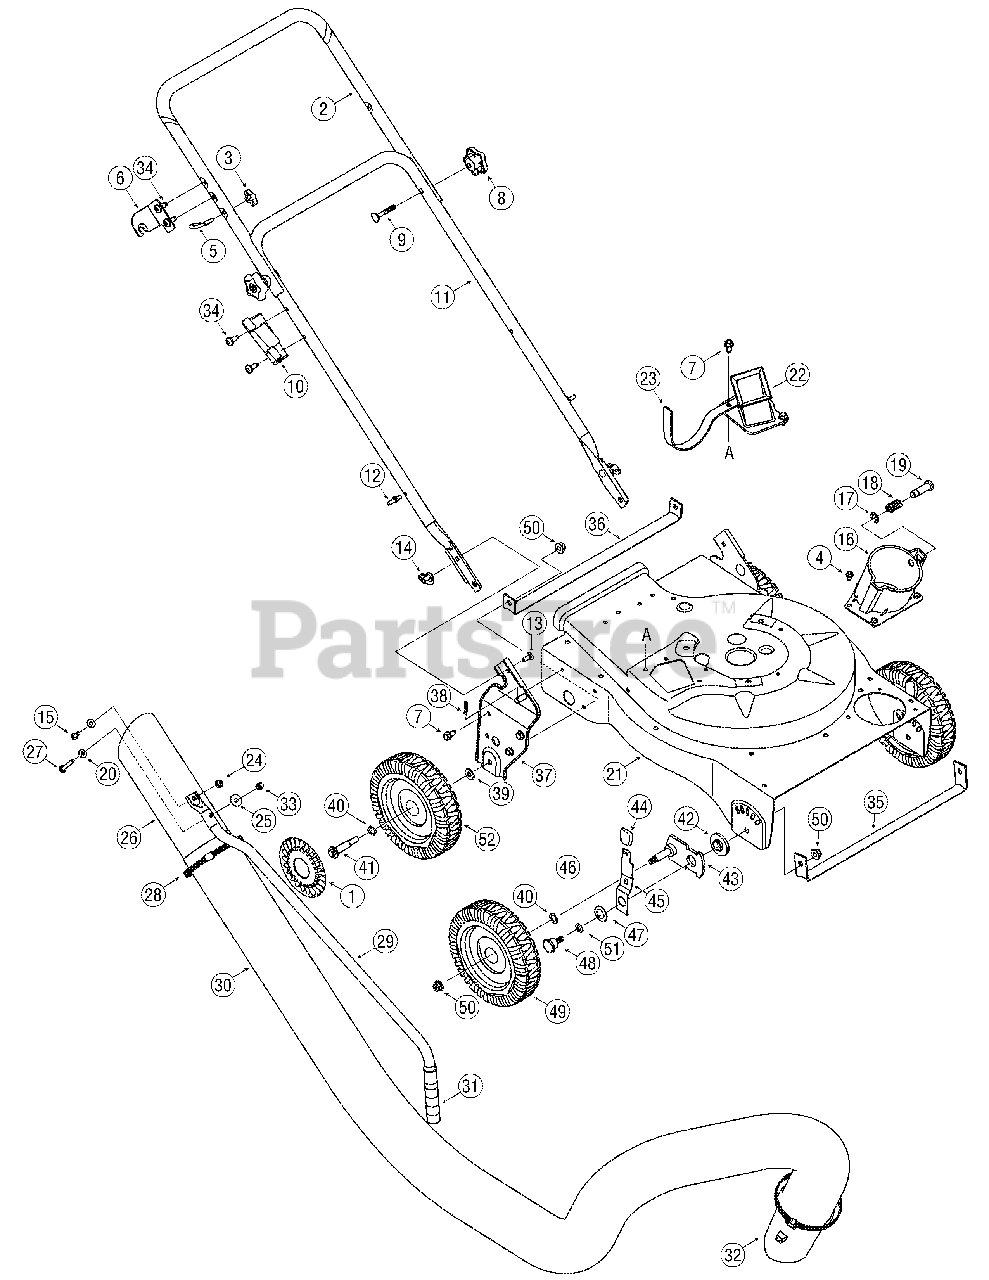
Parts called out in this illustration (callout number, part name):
1	Radial Spoke Hubcap
4	Screw, 1/4-20 x.500
7	Hex Cap Screw 5/16-12 x.750
8	Star Knob 5/16-18
9	Carriage Bolt
10	Nozzle Handle Clip
13	Carriage Screw 1/4-20 x.75
14	Wing Nut 1/4-20
15	Hex Cap Screw 1/4-20 x.620
16	Hose Base Adapter Assembly
17	E Ring.500 Dia
18	Compression Spring
19	Clevis Pin
20	Flat Washer.271 ID x.630 OD
26	Hose Nozzle
27	Hex Cap Screw 1/4-20 x 2.625
28	Adjustment Clamp
30	Vacuum Hose
31	Handle Grip
32	Hose Adapter
33	Cap Lock Nut, 1/4-20
34	TT Screw, 5/16-18 x .750
38	Cotter Pin
39	Bell Washer.401 ID x.870 OD
40	Wave Washer.531 ID x.781 OD
41	Shoulder Screw 3/8-16
42	Height Adjustment Bearing
43	Pivot Arm Assembly
44	Height Adjustment Knob
45	Spring Lever
46	Height Lever Assembly
47	Bell Washer.760 ID x.25 OD
48	Shoulder Screw,.750 x.500
49	Wheel 8 x 2.125
50	Flange Lock Nut, 3/8-16
51	Thrust Washer.375 ID x.70 OD
52	Wheel 9 x 2.125
